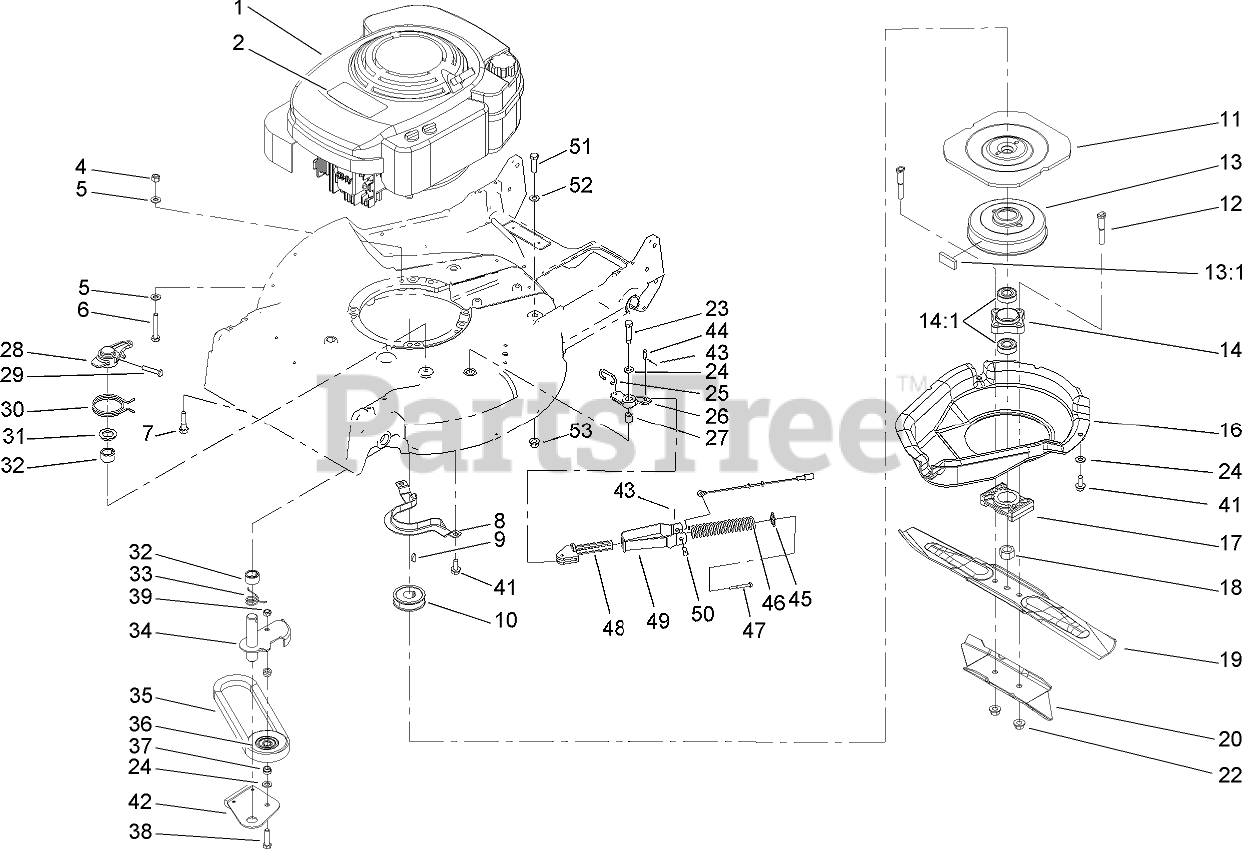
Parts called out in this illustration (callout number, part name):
2	DECAL-ENGINE, HONDA
4	NUT-LOCK, NI
5	WASHER-PLAIN
6	SCREW-HH
7	SCREW-SHOULDER
8	BRACKET-GUIDE, BELT
9	KEY-WOODRUFF
10	PULLEY-DRIVER
11	FLYWHEEL-BBC
12	BOLT-BLADE
13	BRAKE DRUM ASM
13:1	DAMPENER-VIBRATION
14	HUB ASM
14:1	BEARING-BALL
16	SHIELD
17	SPACER-BLADE
18	NUT-BLADE
19	Blade
20	STIFFENER-BLADE
22	NUT-LOCK
23	SCREW-HH
24	WASHER-PLAIN
25	LINK-CONTROL
26	BELLCRANK
27	SLEEVE-BELLCRANK
28	LEVER
29	SCREW-HH
30	SPRING-TORSION
31	WASHER
32	BEARING
33	SPRING-TORSION
34	ARM-IDLER
35	V-BELT
36	PULLEY-IDLER
37	SPACER-PULLEY, IDLER
38	SCREW-HH
39	NUT-LOCK, NI
41	SCREW-HWHTF
42	BRAKE PLATE ASM
43	PIN-COTTER
44	PIN-SPRING
45	RETAINER-SPRING
46	SPRING
47	SCREW-HWHTF
48	GUIDE-SPRING
49	BRACKET-SPRING
50	PIN-CABLE
51	SCREW-HH
52	WASHER-HARDENED
53	NUT-LOCK, NI
